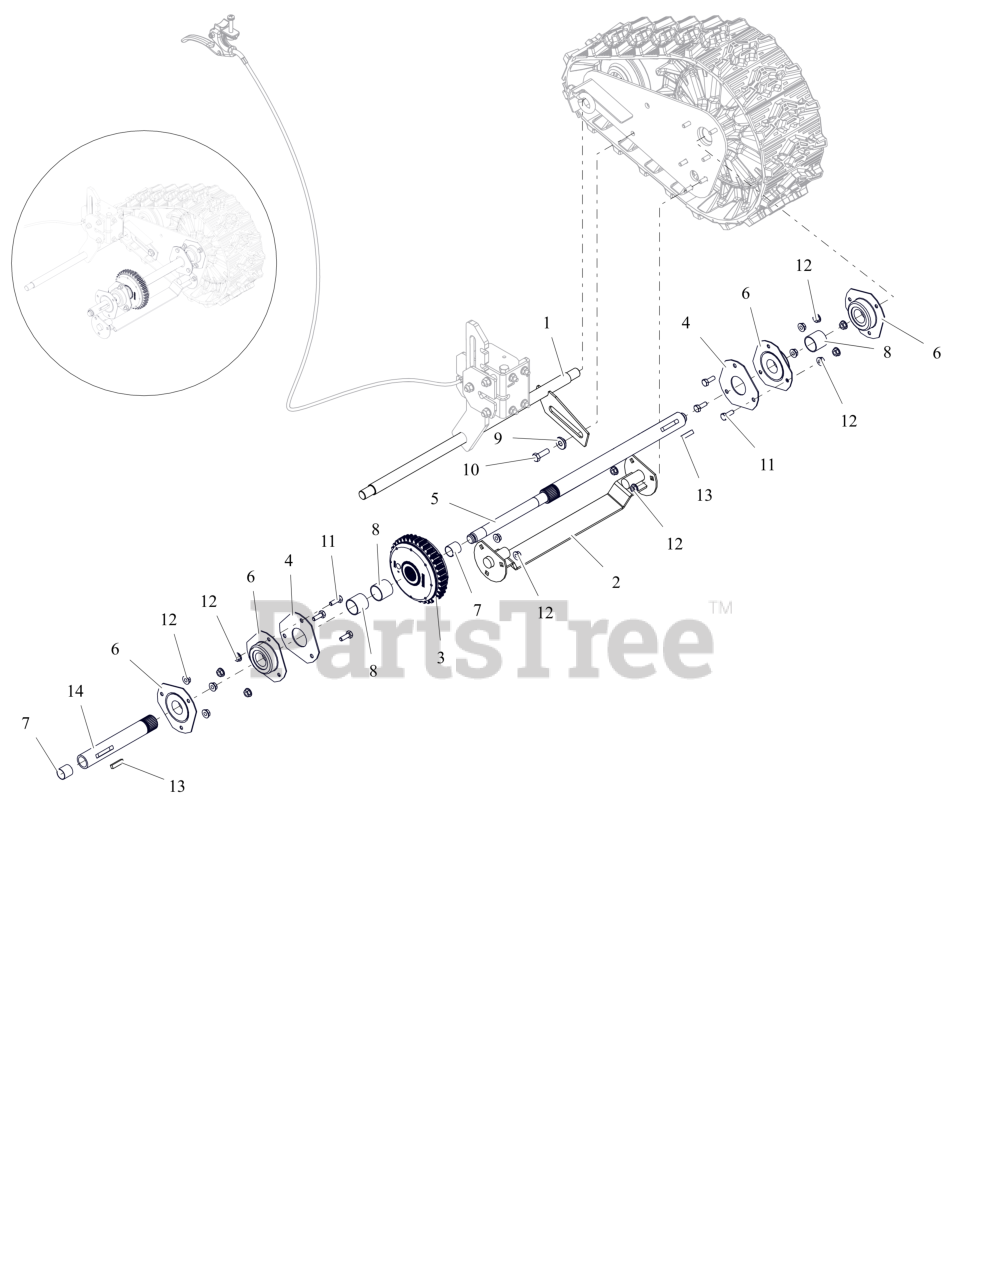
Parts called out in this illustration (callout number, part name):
1	AXLE, REAR - DELUXE TRACK
2	MOUNT- COMPACT RAPID TRACK
3	DIFFERENTIAL, AUTOMATIC
4	PLATE, BEARING SPACER
5	AXLE,LONG - TRACK (DIFF)
6	BRG-FLG 1.003/1.000 3 BOLT
7	BSHG-SLV .706X.764X.75 BRZ
8	BSHG-SLV, 1.012X1.125X1.00
9	BSHG-FLG .325X.499X.3X.875
10	BLT,HEX .31-18X1.00 G5 ZCC
11	BLT, HEX .25-20X.75 G5 ZCC
12	NUT-LK-CTR-FLG .25-20 ZC120
13	KEY-RECT .25X.188X1.00
14	AXLE,SHORT TRACK W/BUSHINGS
